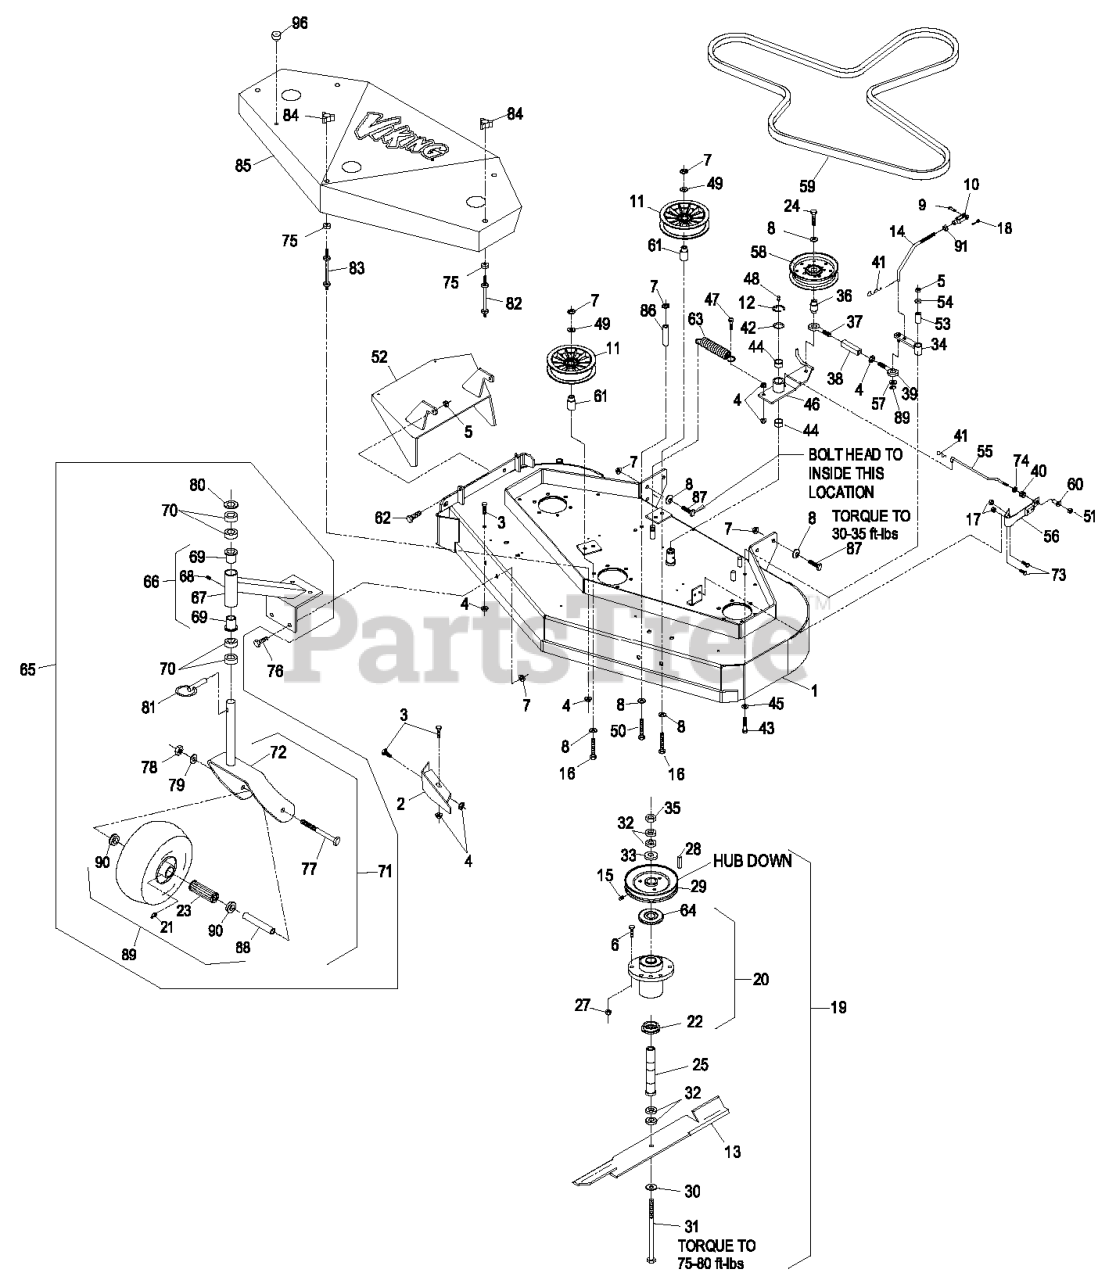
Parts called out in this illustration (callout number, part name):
1	DECK-SERVICE, 48
2	BAFFLE-DOGLEG
3	SCREW-HH
5	NUT-LOCK, NI
6	SCREW-HH
7	NUT-HHF, WHIZ
8	WASHER-BELLEVILLE
9	PIN-CLEVIS
10	YOKE-ADJUSTABLE
11	PULLEY,IDLER 5"
12	RING-RETAINING, EXT
14	ARM-LINKAGE, ASSIST
15	SCREW-SET
16	SCREW-HH
17	NUT-LOCK, NI
18	PIN-COTTER
19	ASM, CUTTER HOUSING OUTER
20	KIT, CUTTER HOUSING
21	FITTING-GREASE
22	SPACER-GUARD, BOTTOM
23	BEARING
24	SCREW-HH
25	TUBE-SPINDLE, SHORT
26	RING-RETAINING, EXT
27	NUT-LOCK, NI
29	SHEAVE
30	WASHER-SPRING
31	SCREW-CAP, HH
33	WASHER-RETAINER, SHEAVE
34	ARM-ASSIST, 32/36
35	NUT-HEX
36	BUSHING-ENGAGEMENT
37	EYEBOLT-THREAD, LH
38	BODY-TURNBUCKLE
39	EYEBOLT-THREAD, RH
40	SPRING-COMPRESSION
41	PIN-COTTER
42	WASHER-SPINDLE
43	SCREW-HH
44	SLEEVE-BEARING
45	WASHER-SPRING
46	IDLER ARM ASM
47	SCREW-HH
48	FITTING-GREASE
49	WASHER-FLAT
50	SCREW-HH
51	NUT-LOCK, NI
52	WLD,CHUTE 48
53	TUBE-PIVOT
54	WASHER-FLAT
55	ROD-BRAKE
56	PAD AND SPRING ASM
57	WASHER-PLAIN
59	BELT,BLADE 48
60	SPACER-FLANGED
62	SCREW-HH
63	SPRING-EXTENSION
64	GUARD-BEARING, TOP
66	ASM,CSTR SUPPORT W/WEIGHT
68	FITTING-GREASE
69	BEARING-FLANGED
70	SPACER-CASTER
71	ASM,CASTER/WHEEL
73	SCREW-HH
74	RING-PUSH ON
76	SCREW-HH
77	SCREW-HH
78	NUT-HH
79	WASHER-LOCK
80	WASHER-FLAT
82	STUD-SHIELD, BELT (SHORT)
83	STUD-SHIELD, BELT (LONG)
84	KNOB-3 PRONG
87	SCREW-HH
89	KIT, SP CASTER WHEEL REPL
90	BUSHING
91	NUT-HEX
